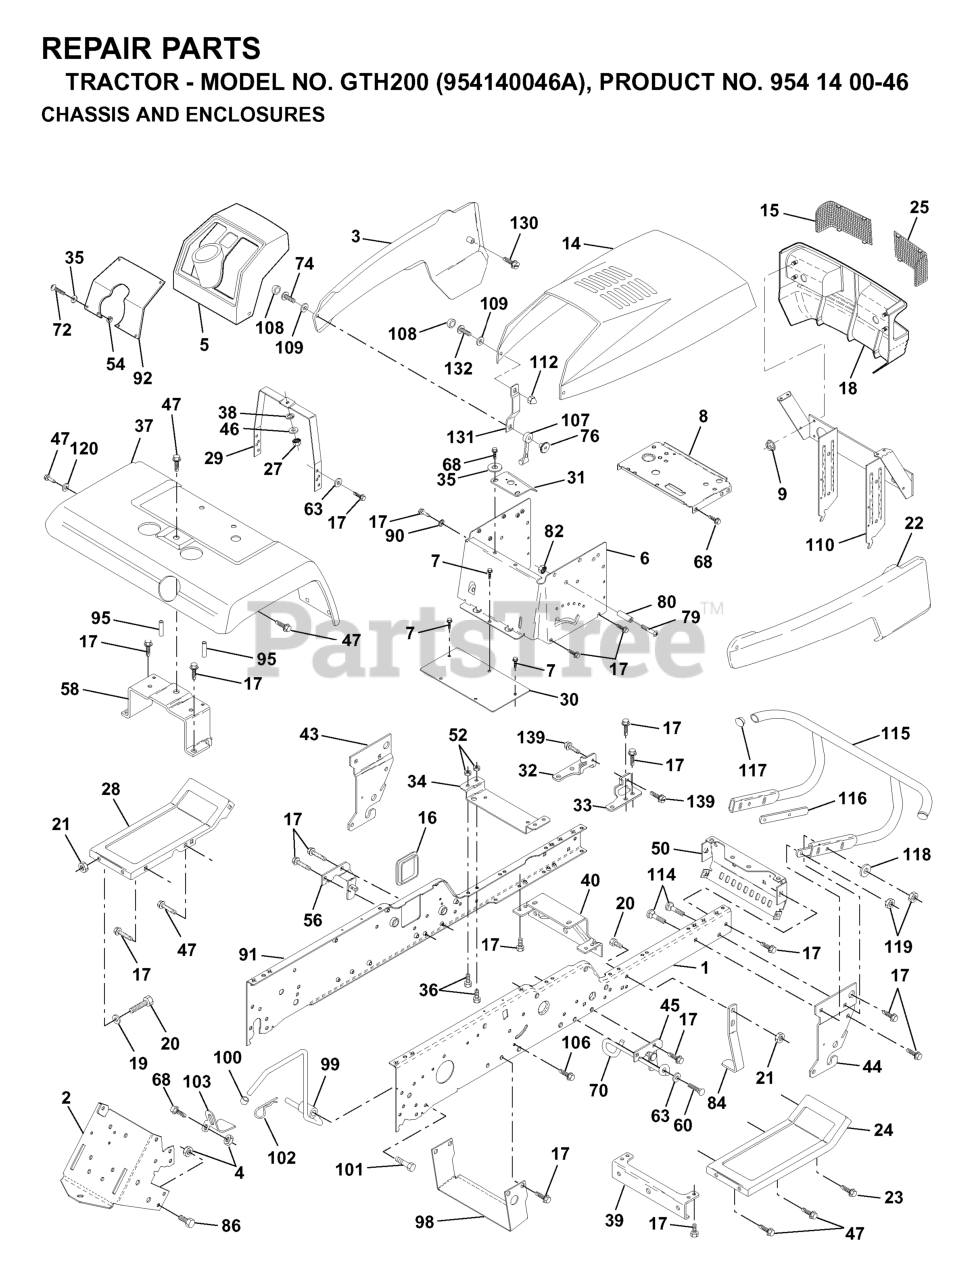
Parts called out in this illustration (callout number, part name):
1	RAIL, FRAME RH
2	DRAWBAR-GT
3	SIDE PANEL LH
4	Nut, Lock Hex 7/16 Unc
6	DASH VGT, LOWER
7	SCREW
8	SUPPORT, BATTERY
9	PAL NUT LT
14	HOOD ASM PNT
16	COVER ACCESS
17	SCREW
18	GRILLE.ASM.HUSQVARNA.YTGT
19	WASHER
20	BOLT
22	PANEL ASM SD RH
23	SCREW GTV
24	FOOTREST RH
25	LENS.RH.HUSQVARNA.YTGT.CL
27	NUT
28	FOOT REST LH
29	DASH SUPT YP
30	SADDLE.HYDRO.95
31	BRACKET SUPT 1-PC VGT STEERING
32	FRAME PIVOT BRKT ASSY LH
33	FRAME PIVOT BRKT ASSY RH
34	ENGINE SUPPORT BRKT
35	WASHER
36	BOLT.FIN.HEX.5/16-18X3/4
37	FENDER
38	LOCKWASHER
39	FRONT AXLE BRACKET
40	BRACKET, SUPPORT AXLE/ENGINE
43	FRONT SUSPENSION BRKT LH
44	FRONT SUSPENSION BRKT RH
45	BRACKET SUSP RH
50	BRACKET, CHASSIS FRONT
52	NUT.71038.31-18.HEX.NYLOCK
54	NUT
56	BRACKET ASM, SUSP CHASSIS
58	FENDER BRKT
60	SCREW
63	WASHER
68	Screw 5/16-18 x 1/2 Hex, Self Tapping 5/16-18 x 1/2
70	BELT GUIDE
72	Screw, Machine, Truss Head 5/16-18 UNC x 3/4
74	SCREW
76	WELDNUT
79	RP SCREW
82	NUT **
84	MOWER STOP
86	BOLT
90	LOCKWASHER
91	RAIL, FRAME LH
92	DASH PLATE
95	NUT-PUSH YT
98	BRACKET CHASSIS
99	ROD ASMBLY BYPASS
100	CAP
101	SCREW LT
102	RETAINER M
103	BRACKET LOCK BYPASS
106	SCREW
107	LATCH.HOOD.
108	SNAP CAP LT
110	PIVOT ASM GRL/HD
112	NUT
114	BOLT.3/8-14X1.25
116	BRACKET BUMPER
117	PLUG PLASTIC
118	WASHER
120	WASHER
130	Screw, SLTD Hex Hd. W/Pl Washer
131	BRACKET.SUPPORT.HOOD/PANEL.NLA
132	SCREW 10-24X3/8
